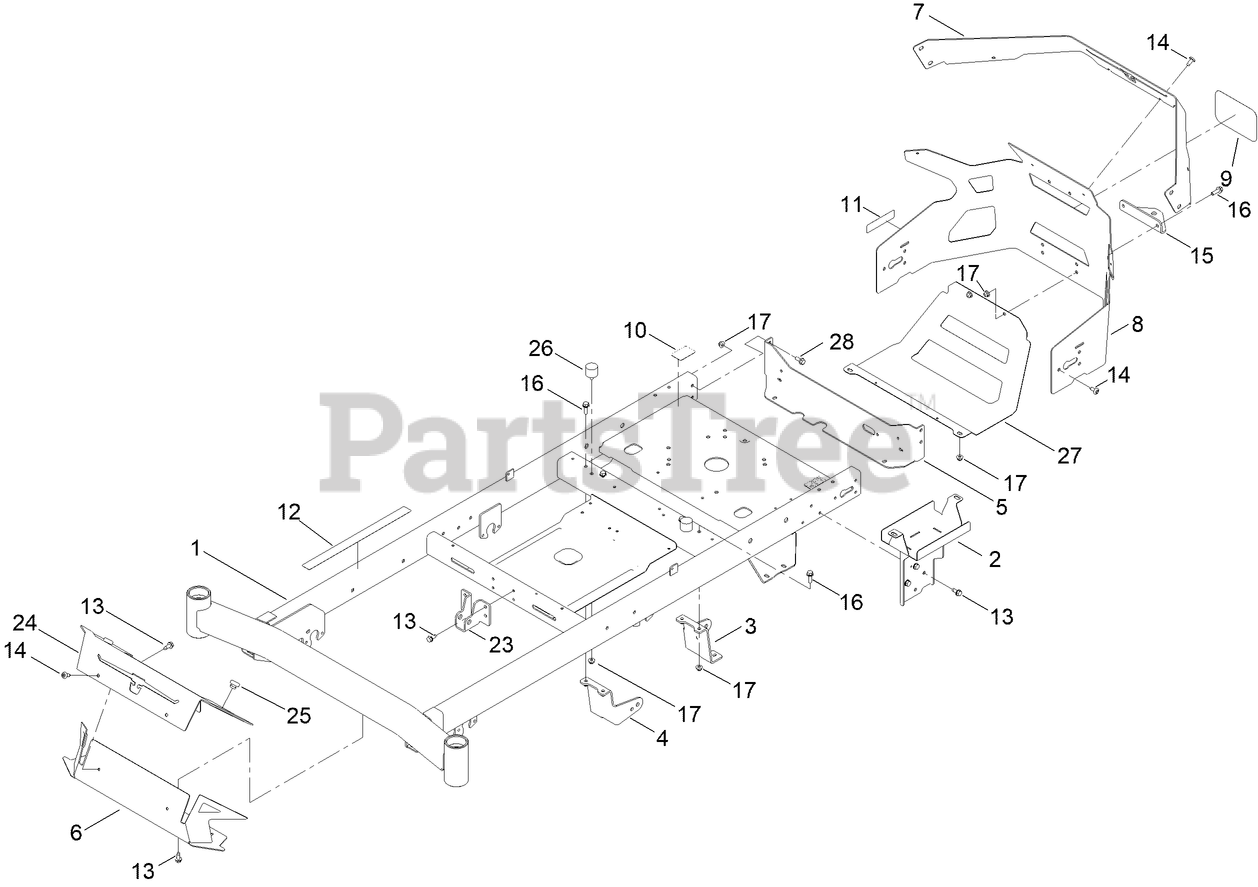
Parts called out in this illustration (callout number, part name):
1	SERVICE ASM-FRAME, TC
2	WA-BATTERY MOUNT
3	MOUNT-DRIVE, LH
4	MOUNT-DRIVE, RH
5	PLATE-MOUNT
6	FOOTREST-TOP
7	PLATE-REAR CLADDING TC
8	GUARD-ENGINE TC
9	DECAL
10	DECAL-BYPASS
11	DECAL-SPARK ARRESTER
12	DECAL-WARNING
13	SCREW-HWHTF
15	BRACKET-HITCH
16	SCREW-HHF
17	NUT-HF
23	BRACKET-MOUNT DAMPER, LOWER
24	PLATE-KICK, MR
25	BUMPER-RUBBER
26	BUMPER-RUBBER
27	GUARD-MUFFLER [BLACK]
28	SCREW-HHF
